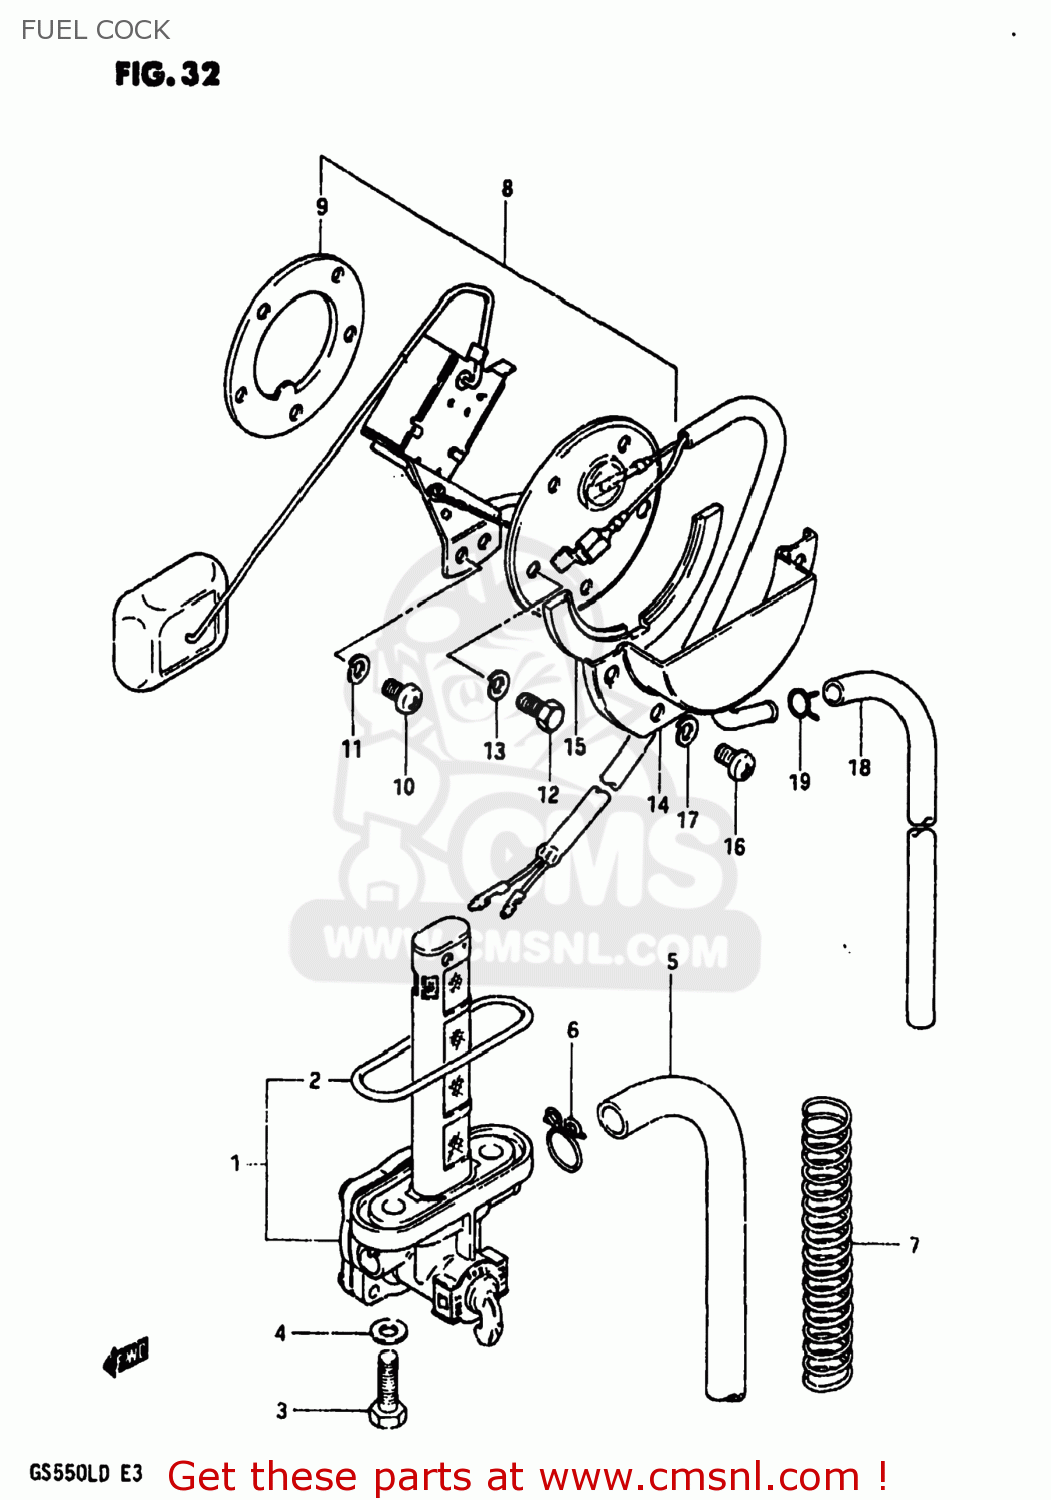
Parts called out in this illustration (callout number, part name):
1	COCK ASSEMBLY,FUEL
2	O RING
3	BOLT(6X20)
4	GASKET
5	HOSE
6	CLIP
7	SPRING
8	GAUGE ASSEMBLY,FUEL LEVEL
9	GASKET,FUEL LEVEL GAUGE (NAS)
10	SCREW
11	LOCK WASHER
12	BOLT
13	LOCK WASHER
14	PLATE,FUEL DRAIN
15	GASKET (NAS)
16	SCREW
17	LOCK WASHER
18	HOSE,FUEL
19	CLIP
